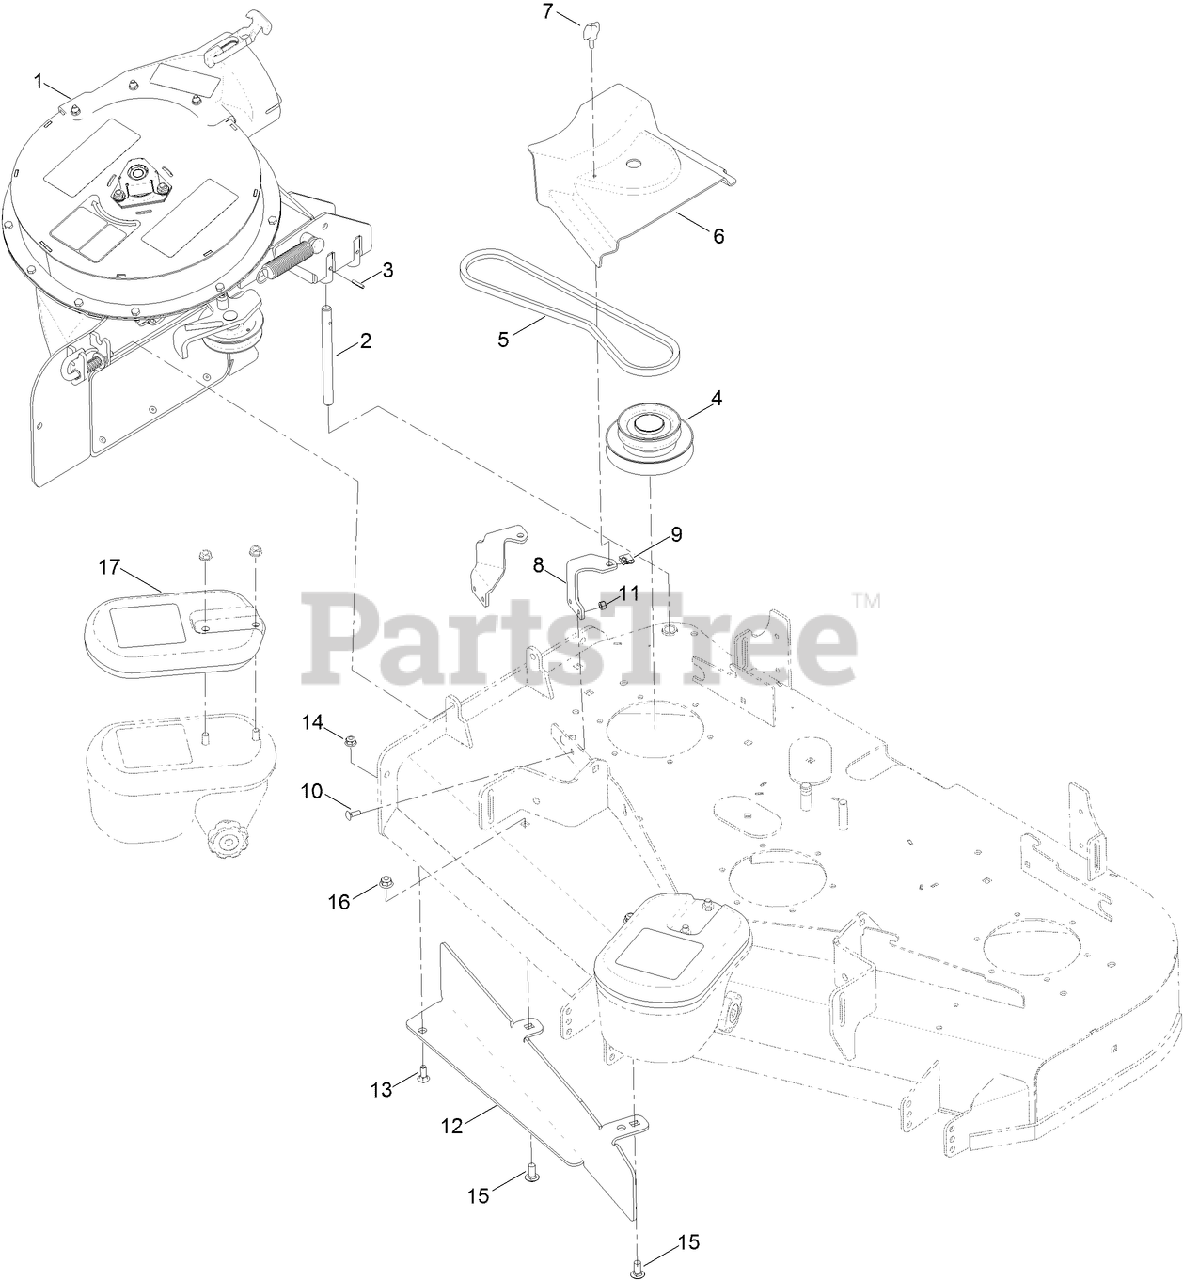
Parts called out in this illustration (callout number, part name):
1	BLOWER ASM
2	SHAFT-CATCHER, GRASS
3	PIN-ROLL
4	DRIVE-JACKSHAFT
5	BELT-V
6	COVER-BELT
8	BRACKET-COVER, BELT
9	NUT-SPEED
10	BOLT-CARR
11	NUT-LOCK, NI
12	BAFFLE-BAGGER
13	SCREW-CARR
14	NUT-HF, NI
15	SCREW-CARR
16	NUT-HF, NI
17	WEIGHT
